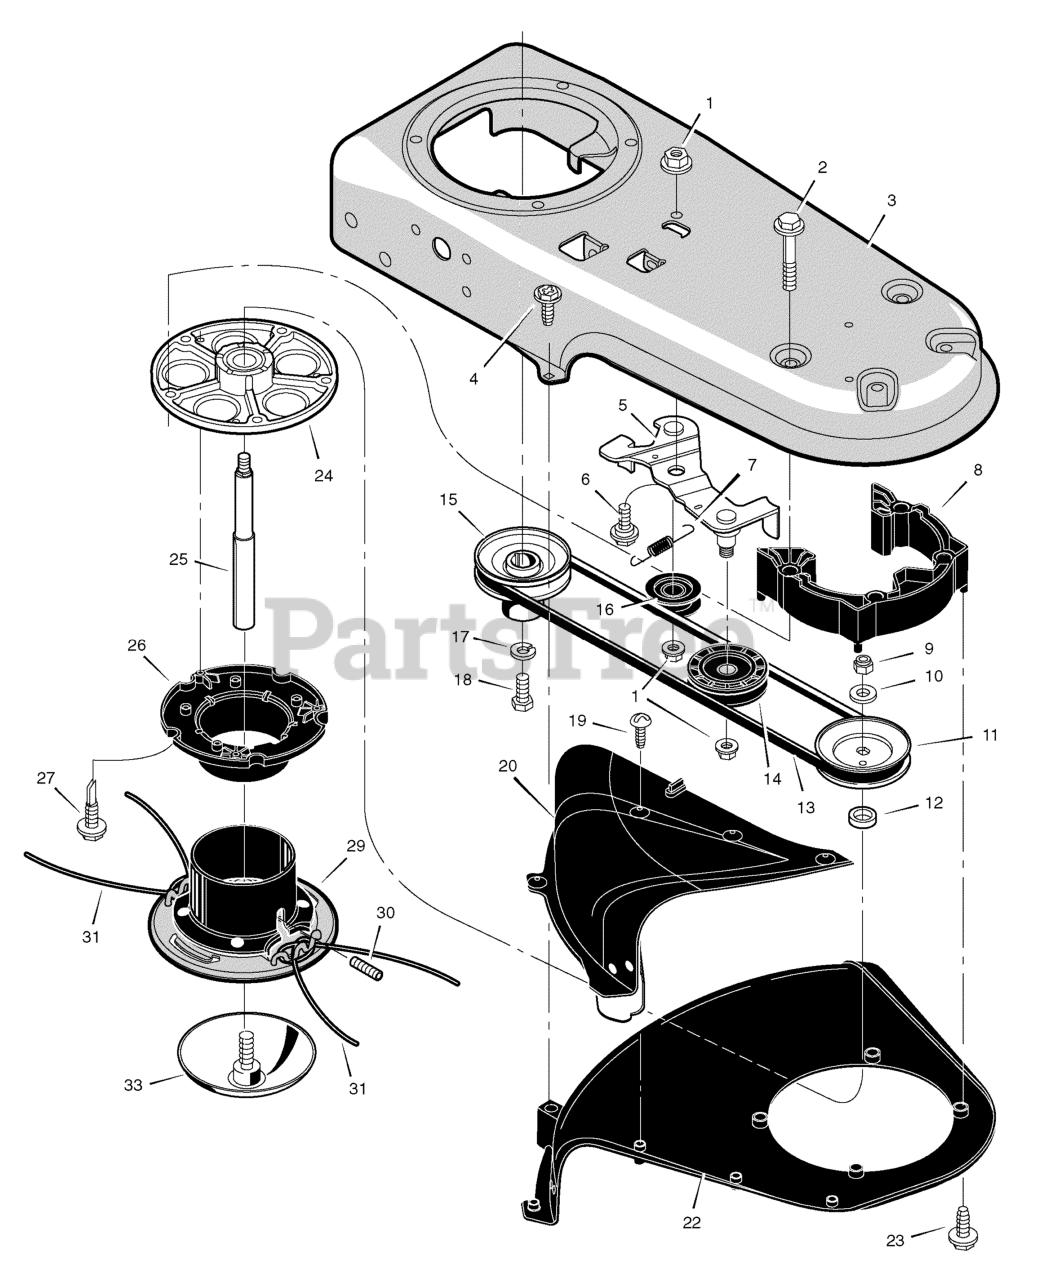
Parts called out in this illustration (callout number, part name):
1	Nut
3	Housing, Trimmer
5	Assembly, Idler
8	Assembly, Spacer
10	Washer
11	Pulley, Cutting Head
13	Belt
14	PULLEY, IDLER, V, 1.88
15	Pulley, Engine
16	Pulley, Idler
17	Lockwasher
20	Assembly, Guard
22	Shield, Trimmer
24	Assembly, Jackshaft Housing
25	Jackshaft
26	Wrap, Upper Weed
29	Assembly, Cutting Disc
30	Screw, Set
31	Line, Cutting
33	Guide Assembly, Metal Height
